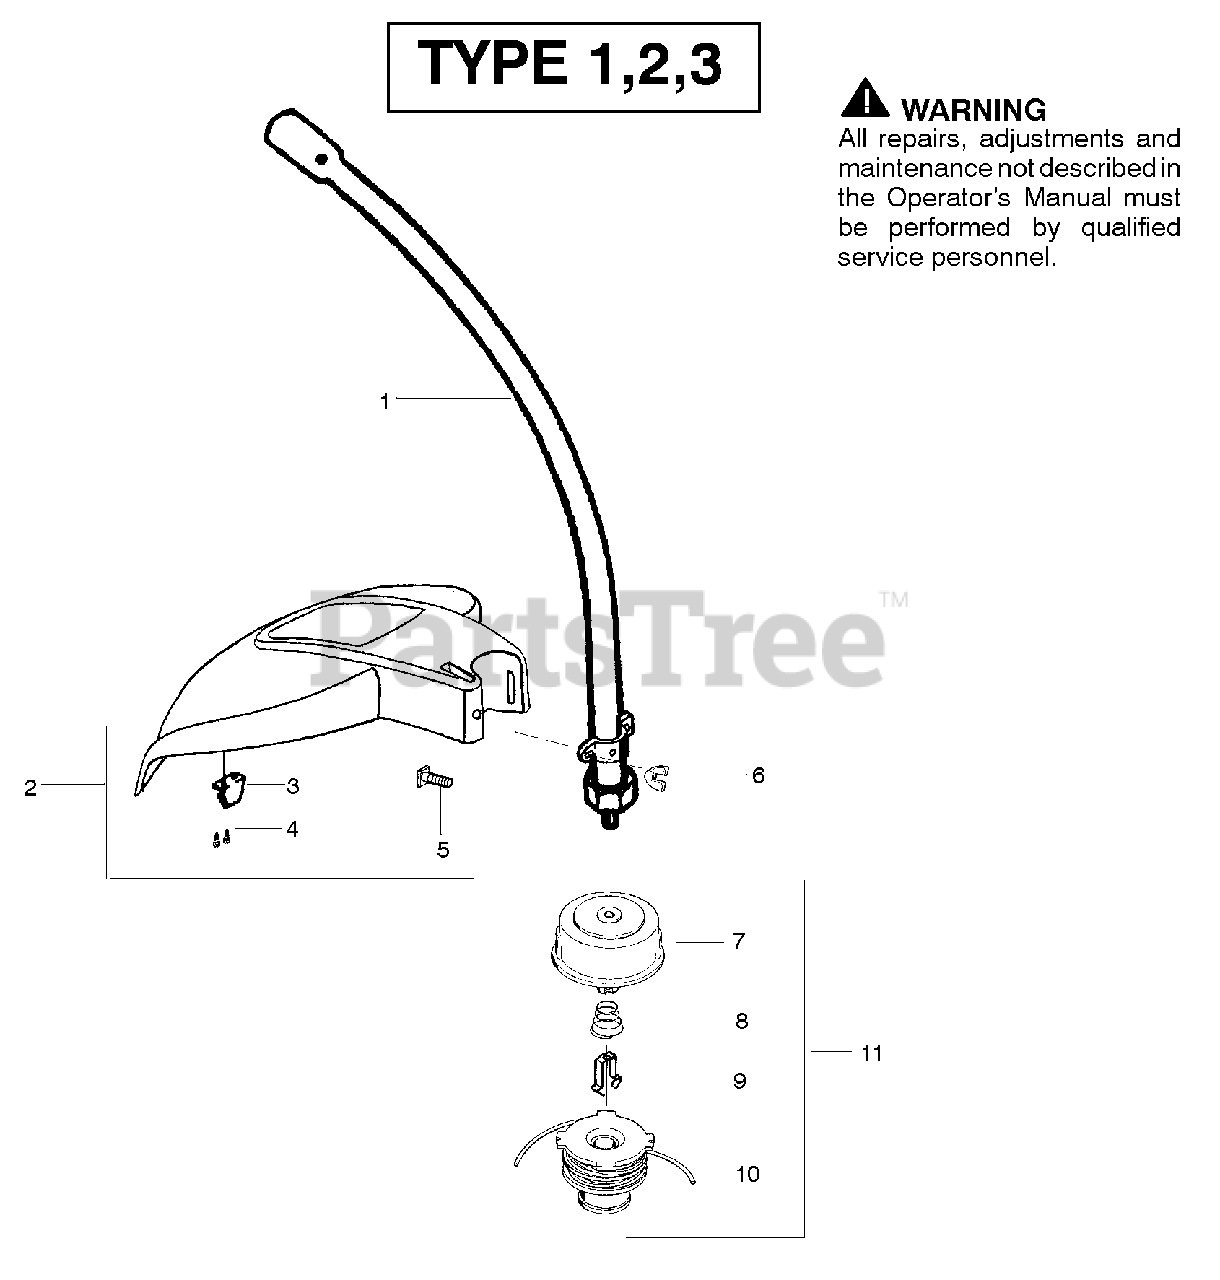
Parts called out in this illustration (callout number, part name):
1	Kit-Lower Shaft Assy.
2	Kit-Shield Assy.
3	Limiter-Line
6	Wingnut
7	Assy-Hub/Arbor
8	Spring-Return
9	Retainer-Spool
10	Accy-Wound Spool
11	Accy-Cutting Head
